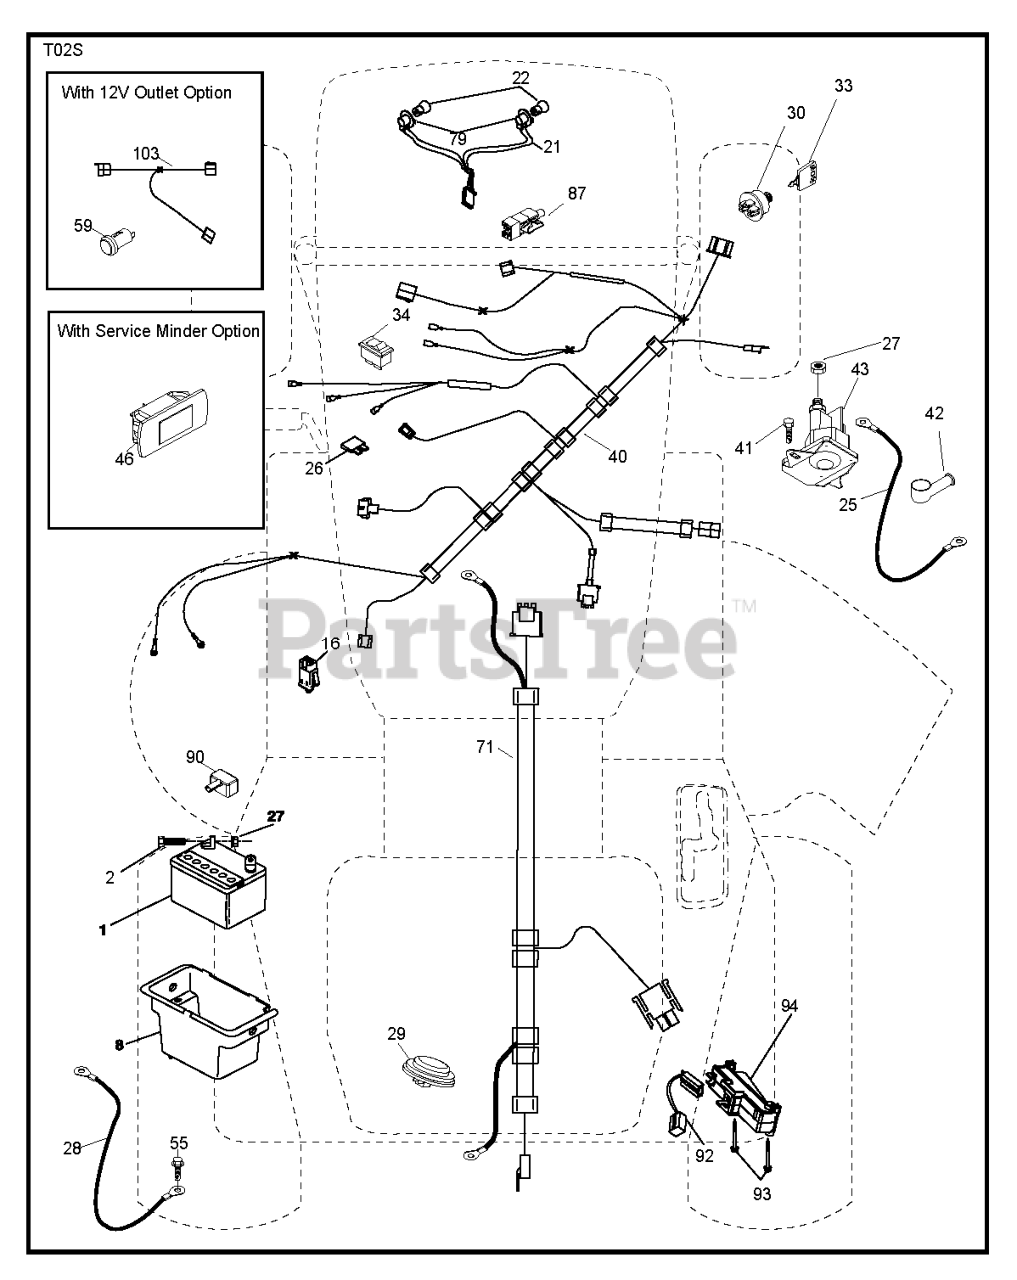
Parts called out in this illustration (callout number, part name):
1	BATTERY 12V .35 AMP
2	BOLT.HEX.1/4.X.3/4.DICHROMATE
8	BOX.BATTERY.MNT.REAR.L
16	SWITCH INTERLOOK PUSH-IN
21	HARNESS.LIGHT W/4152J BULBS
25	CABLE.STARTER.6GA.RED.
26	FUSE 20AMP
27	NUT
28	CABLE.BLACK.18"REAR.BA
29	SWITCH.SEAT.DP W/RAMPS
30	SWITCH.IGN.DELTA.W.LGH.ROS
33	KEY MLD GEN DELTA
40	HARNESS IGN. DASH
41	SCREW
42	TERMINAL COVER
43	SOLENOID.W/BRASS.PLUNGER
55	SCREW 5/16"
71	HARNESS.IGN.CHASS.TEX.REAR.BAT
79	BULB HOLDER ASM.
87	SWITCH.INTRLCK.CLUTCH.
90	COVER, TERMINAL BATTERY
92	HARNESS.PIGTAIL.CONSLE
93	SCREW.PLASTITE
94	MODULE.REVERSE.ROS
